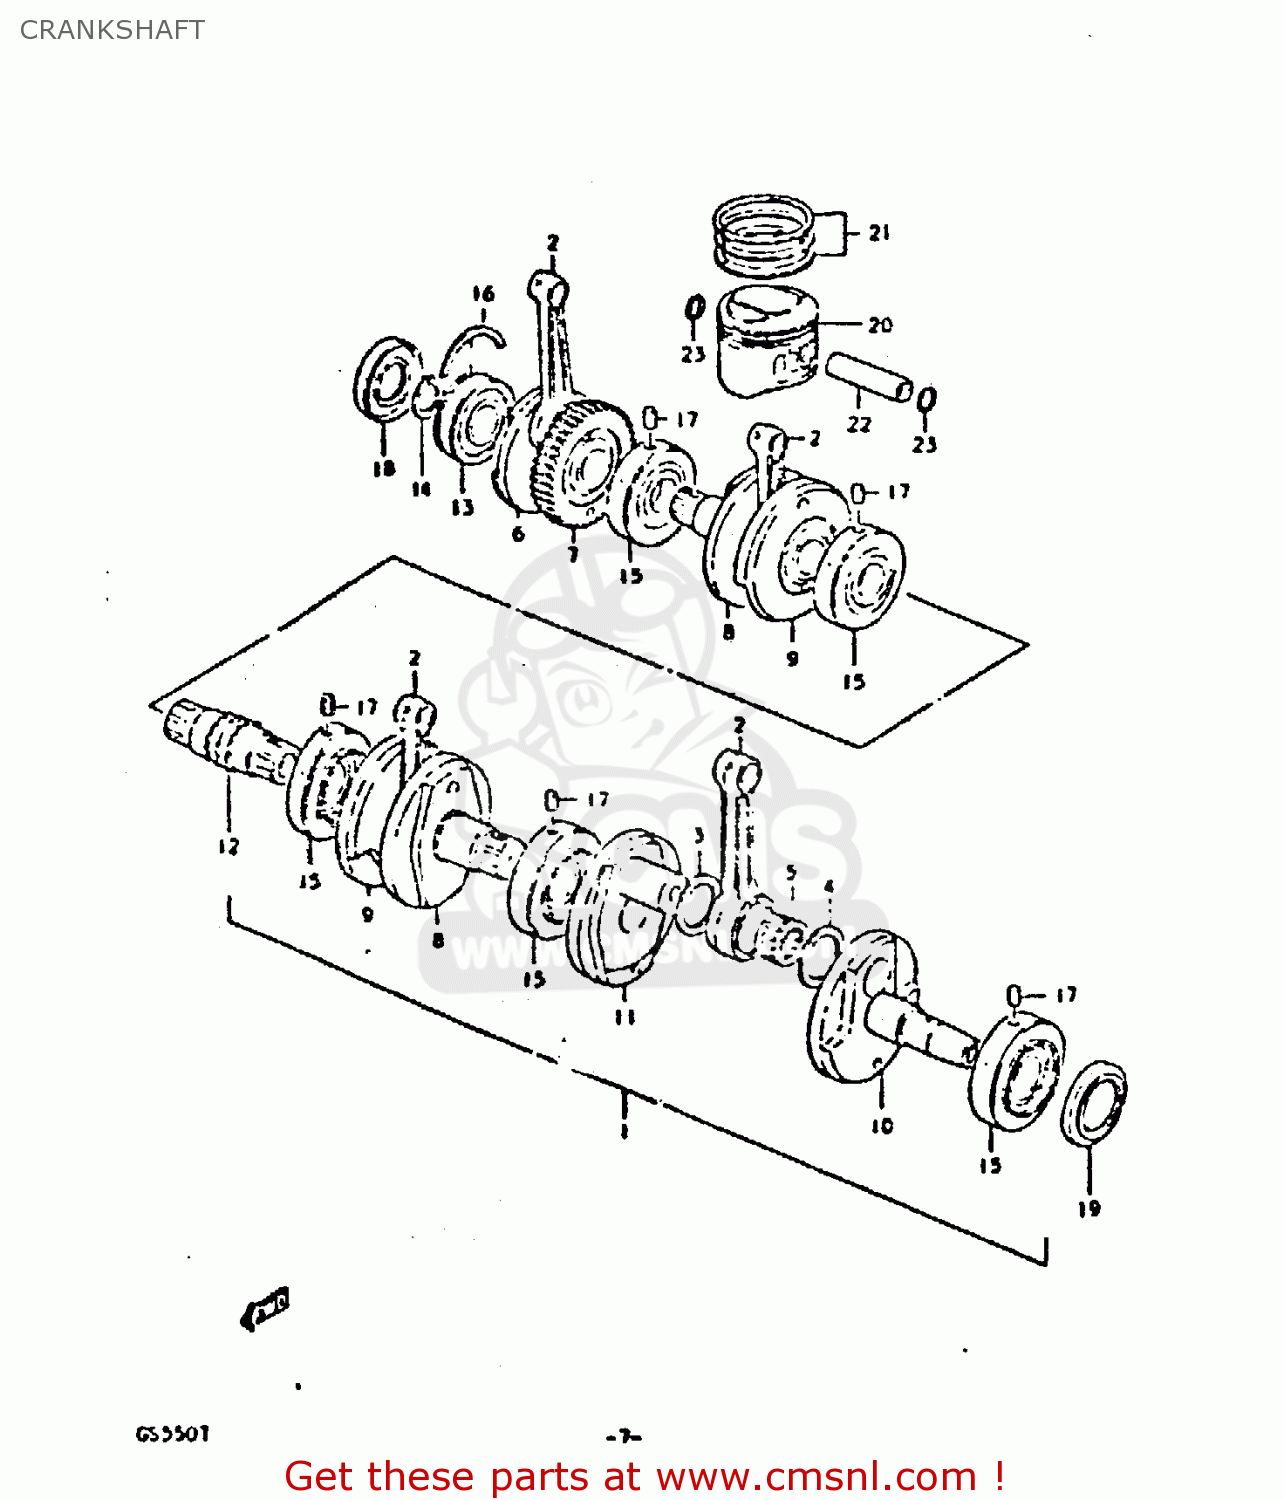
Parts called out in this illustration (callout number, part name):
1	CRANKSHAFT ASSEMBLY
2	ROD,CONNECTING
3	WASHER (28X48X2)
4	WASHER(28X48X1)
5	ROLLER BEARING (28X38X16.8)
6	CRANKSHAFT
7	WEB,CRANK
8	CRANKSHAFT
9	WEB,CRANK,MIDDLE
10	CRANKSHAFT,LEFT
11	WEB,CRANK,LEFT
12	SHAFT,TIMING CHAIN DRIVE
13	BEARING(30X72X19)
14	CIRCLIP,30MM
15	BEARING
16	C RING
17	PIN
18	SEAL,OIL(30X72X11)
19	OIL SEAL
20	PISTON
21	RING SET,PISTON
22	PIN,PISTON 16MM
23	CIRCLIP
